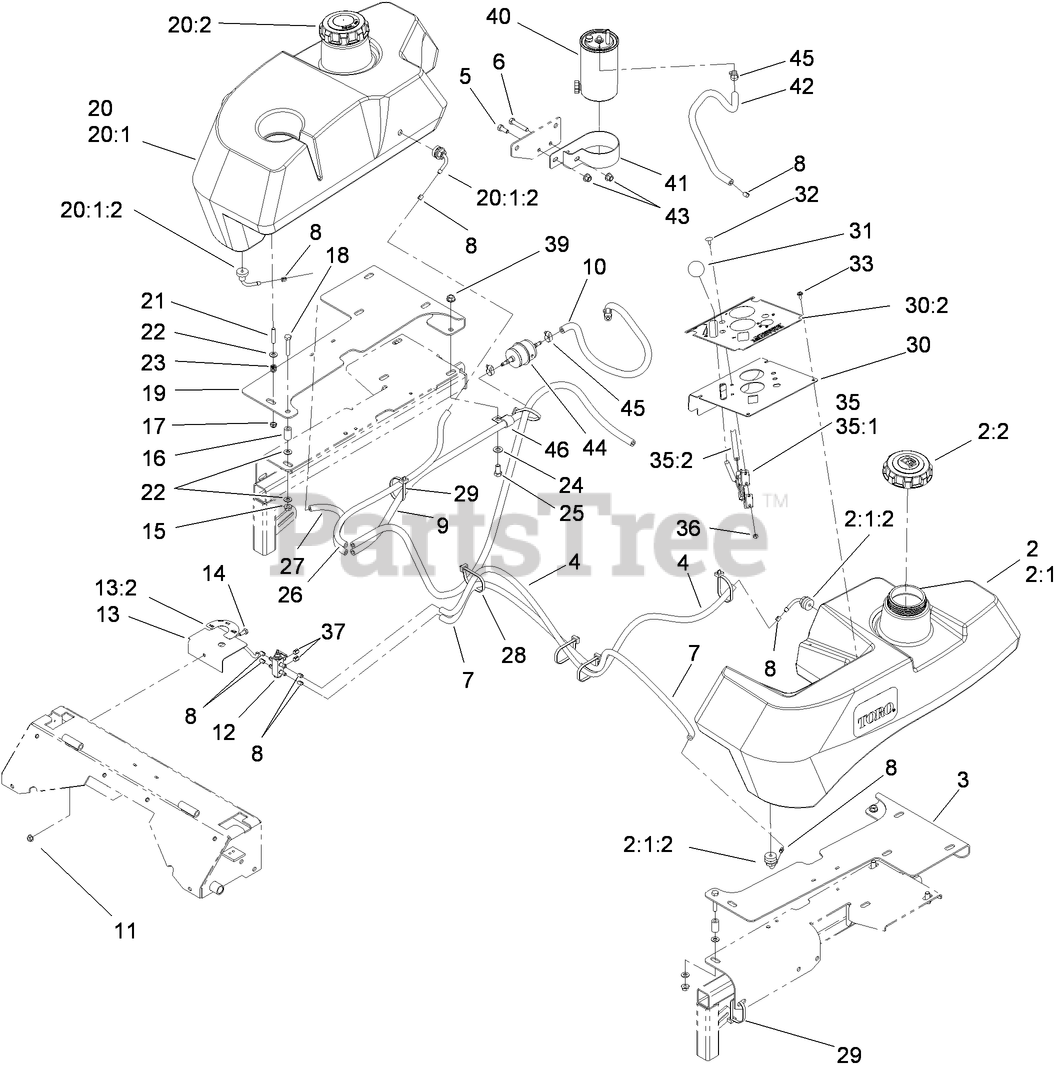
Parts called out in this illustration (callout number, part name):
2	LH FUEL TANK KIT
2:1	Tank-Fuel, LH
2:1:2	Fitting-Fuel, Bulkhead
2:2	BIODIESEL CAP ASM
3	BRACKET-FUEL TANK, LH
4	HOSE-FUEL
5	SCREW-HH
6	SCREW-HH
7	HOSE-FUEL
8	CLAMP-HOSE, FUEL
9	HOSE-FUEL
10	HOSE-FUEL
11	NUT-HF
12	VALVE-FUEL, DUAL FLOW
13	BRACKET-VALVE, FUEL
13:2	DECAL-VALVE, FUEL
14	SCREW-HH
15	NUT-LOCK, NI
16	SPACER
17	NUT-LOCK, NI
18	SCREW-HH
19	BRACKET-FUEL TANK, RH
20	RH FUEL TANK KIT
20:1	Tank-Fuel, RH
20:1:2	Fitting-Fuel, Bulkhead
20:2	BIODIESEL CAP ASM
22	WASHER-PLAIN
23	SPRING-TANK, FUEL
24	WASHER-FLAT
25	SCREW-HH
26	HOSE-FUEL
27	Hose-Fuel
28	HOSE-FUEL
29	TIE-PLASTIC
30	CONTROL PANEL ASM
30:2	DECAL-PANEL, CONTROL
31	KNOB-BALL
32	BOLT-CARR
33	SCREW-PPH
35	THROTTLE CONTROL CABLE ASM
35:1	LEVER-THROTTLE
35:2	CABLE-THROTTLE
36	NUT-LOCK, NI
37	CLAMP-HOSE, FUEL
39	NUT-HHF, WHIZ
40	ELEMENT-FILTER, FUEL/WATER
41	BRACKET-FILTER, FUEL
42	HOSE-FUEL
43	NUT-LOCK, NI
44	FILTER-INLINE
45	CLAMP-WORM
46	CLAMP-J
